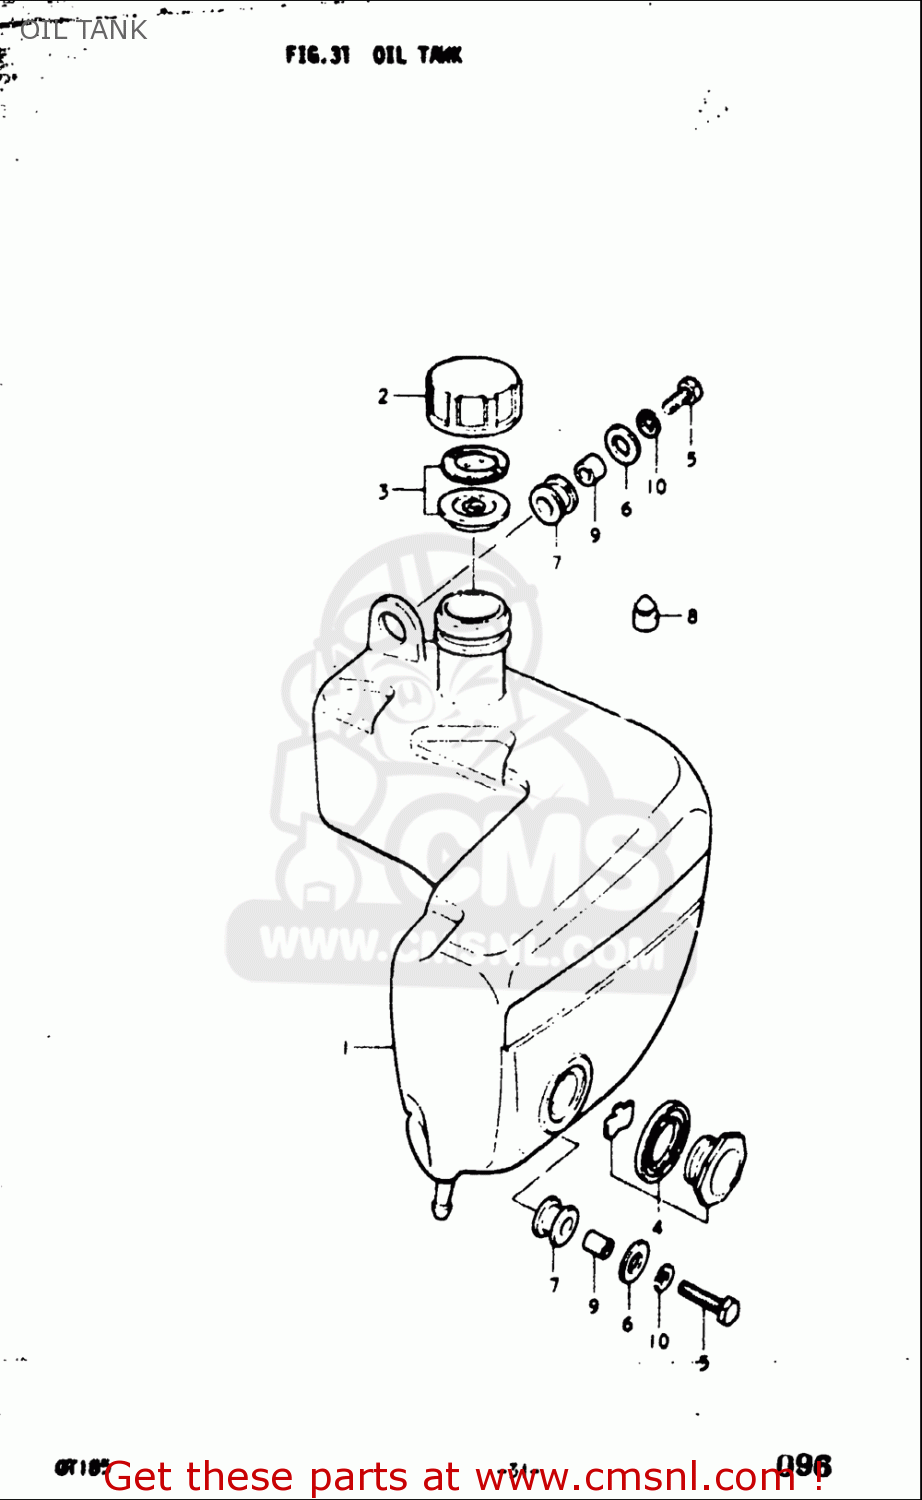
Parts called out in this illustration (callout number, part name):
2	CAP,OIL TANK
3	GASKET SET (NAS)
4	LENS SET,OIL LEVEL
5	BOLT
6	WASHER(6.5X18X1.6)
7	CUSHION
8	CUSHION
9	SPACER(6.5X10X10)
10	WASHER,LOCK
